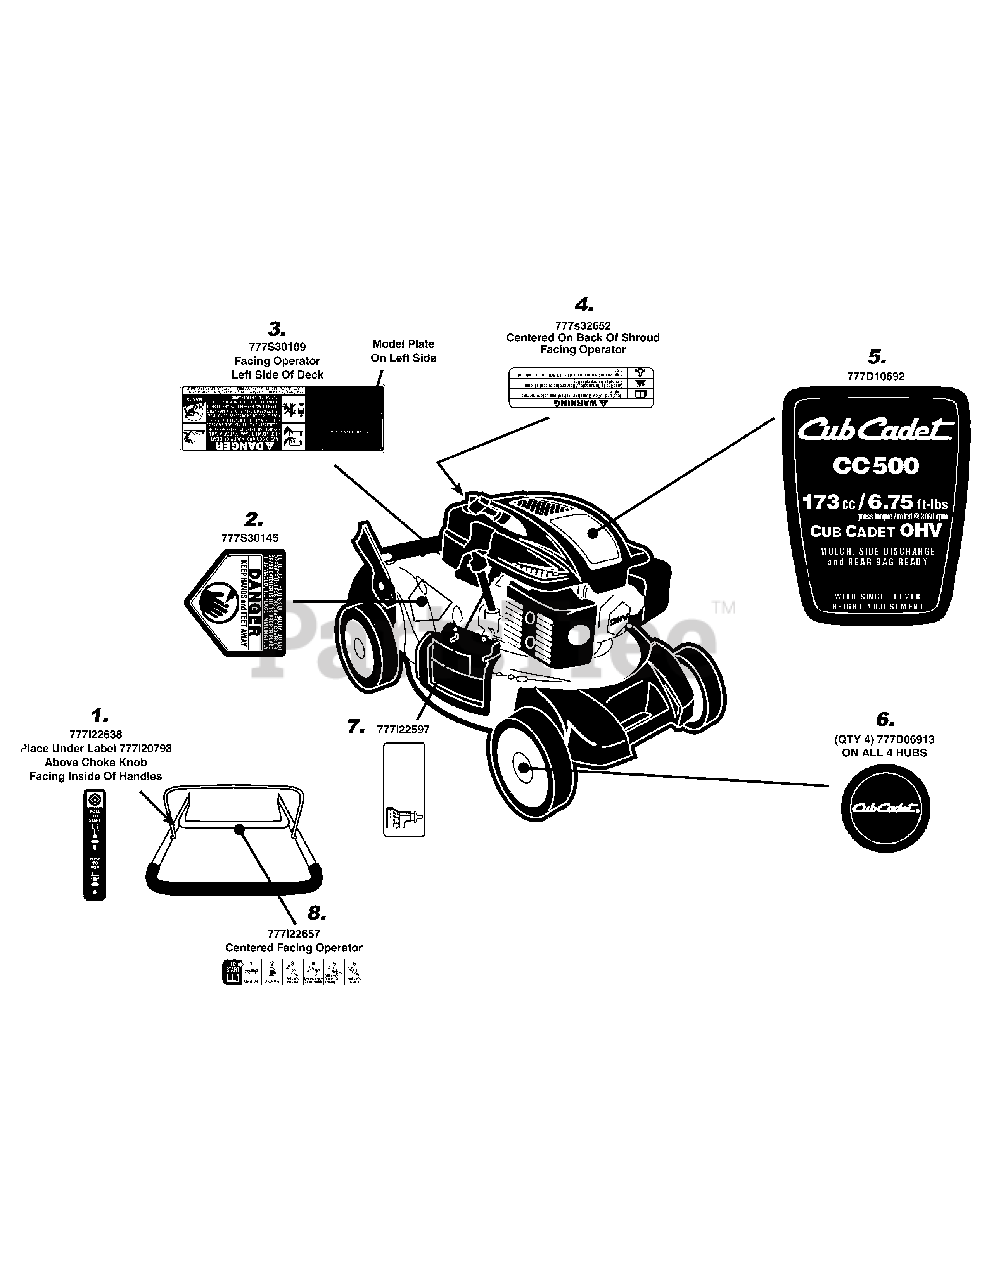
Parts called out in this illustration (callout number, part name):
1	LABEL-MOWER HANDLE:CHOKE START/RUN
2	LABEL
3	LABEL-MOWER DANGER
4	LABEL:MOWER:ENGINE SHROUD
5	LABEL-CC500 ENG SHROUD
6	LABEL-HUB CAP
7	LABEL:MOWER SHROUD
8	LABEL-MOWER HANDLE
